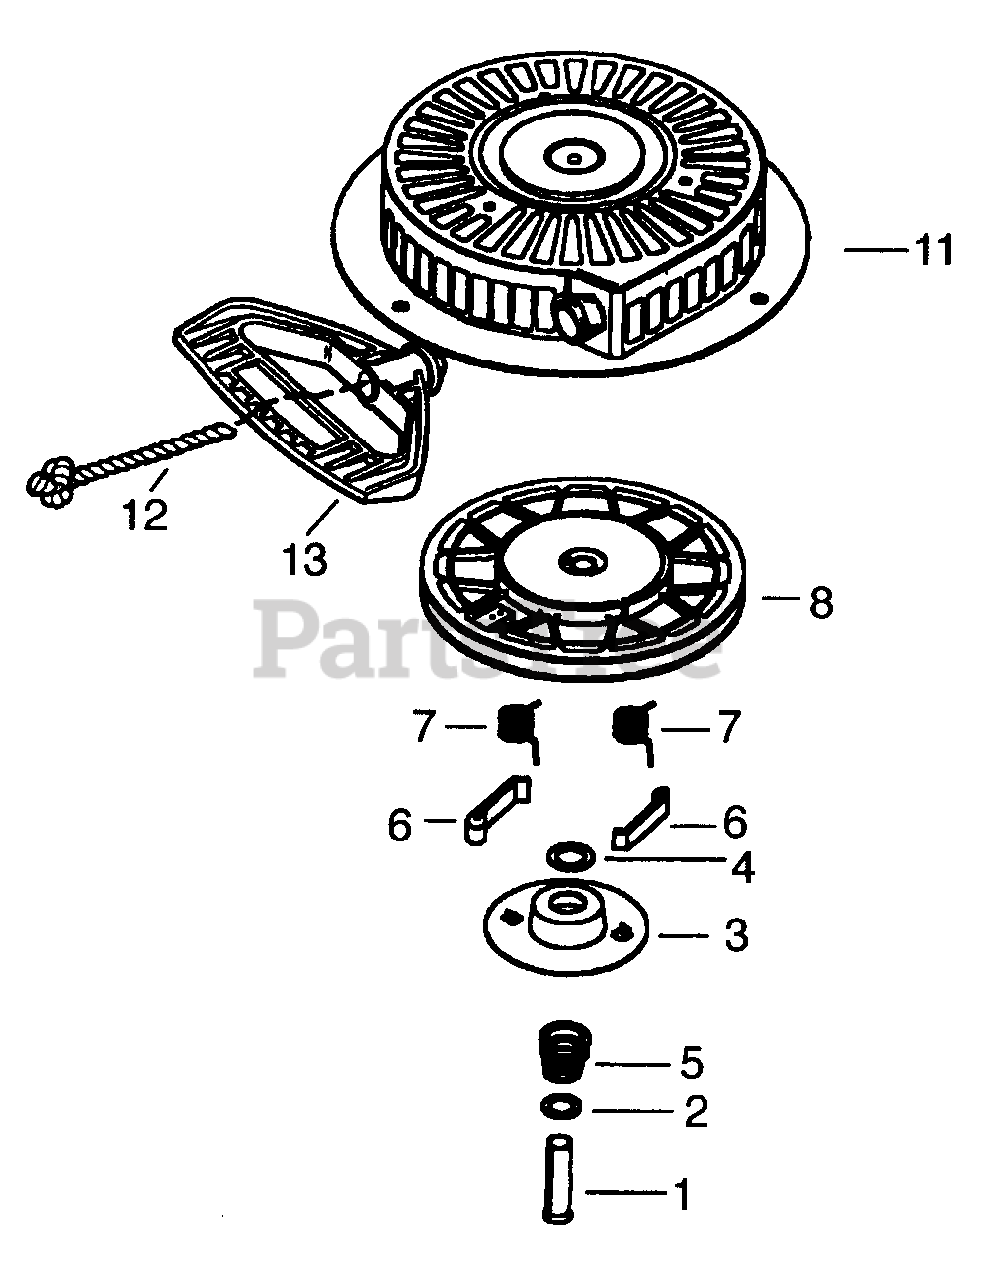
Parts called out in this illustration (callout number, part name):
1	Spring Pin
5	Brake Spring
6	Starter Dog
7	Dog Spring
8	Pulley Rewind Spring Assy
11	Starter Housing Assy
12	Starter Rope
13	Mitten Grip Handle
